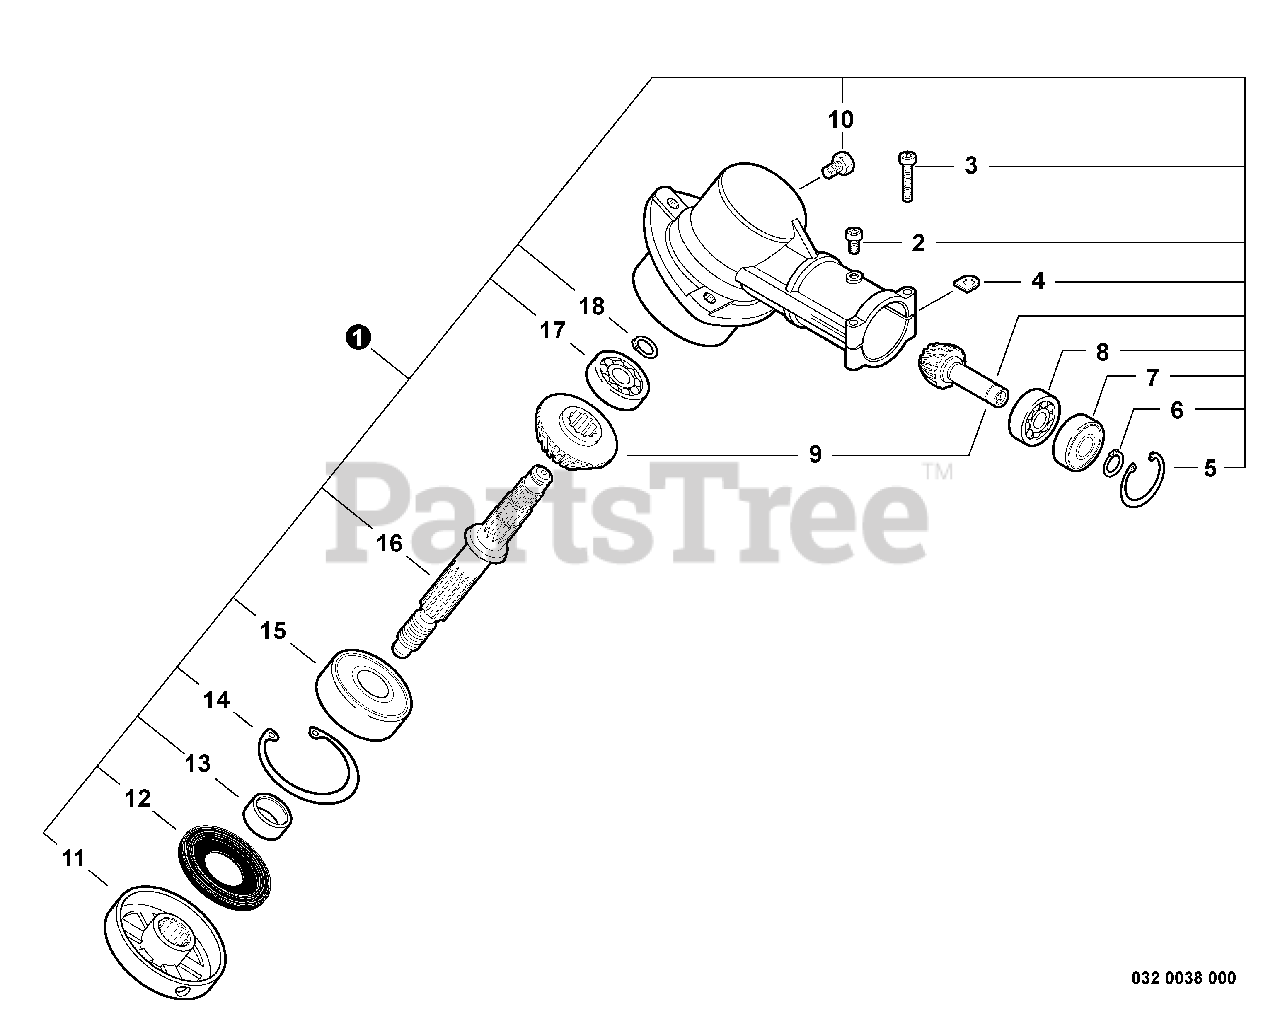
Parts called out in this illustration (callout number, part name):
1	GEAR CASE ASSY
2	SCREW - 5X10
3	SCREW - 5X25
5	RING, RETAINING - 22
6	RING, RETAINING - 10
7	BEARING, BALL - 6900Z
8	BEARING, BALL - 6900
9	GEAR SET - BEVEL
10	BOLT - 8X8
11	ADAPTOR, BLADE - UPPER
12	SEAL, OIL
14	RING, RETAINING - 32
15	BEARING, BALL - 6201
16	GEAR - SHAFT
17	BEARING, BALL - 609
18	RING, RETAINING - 12
